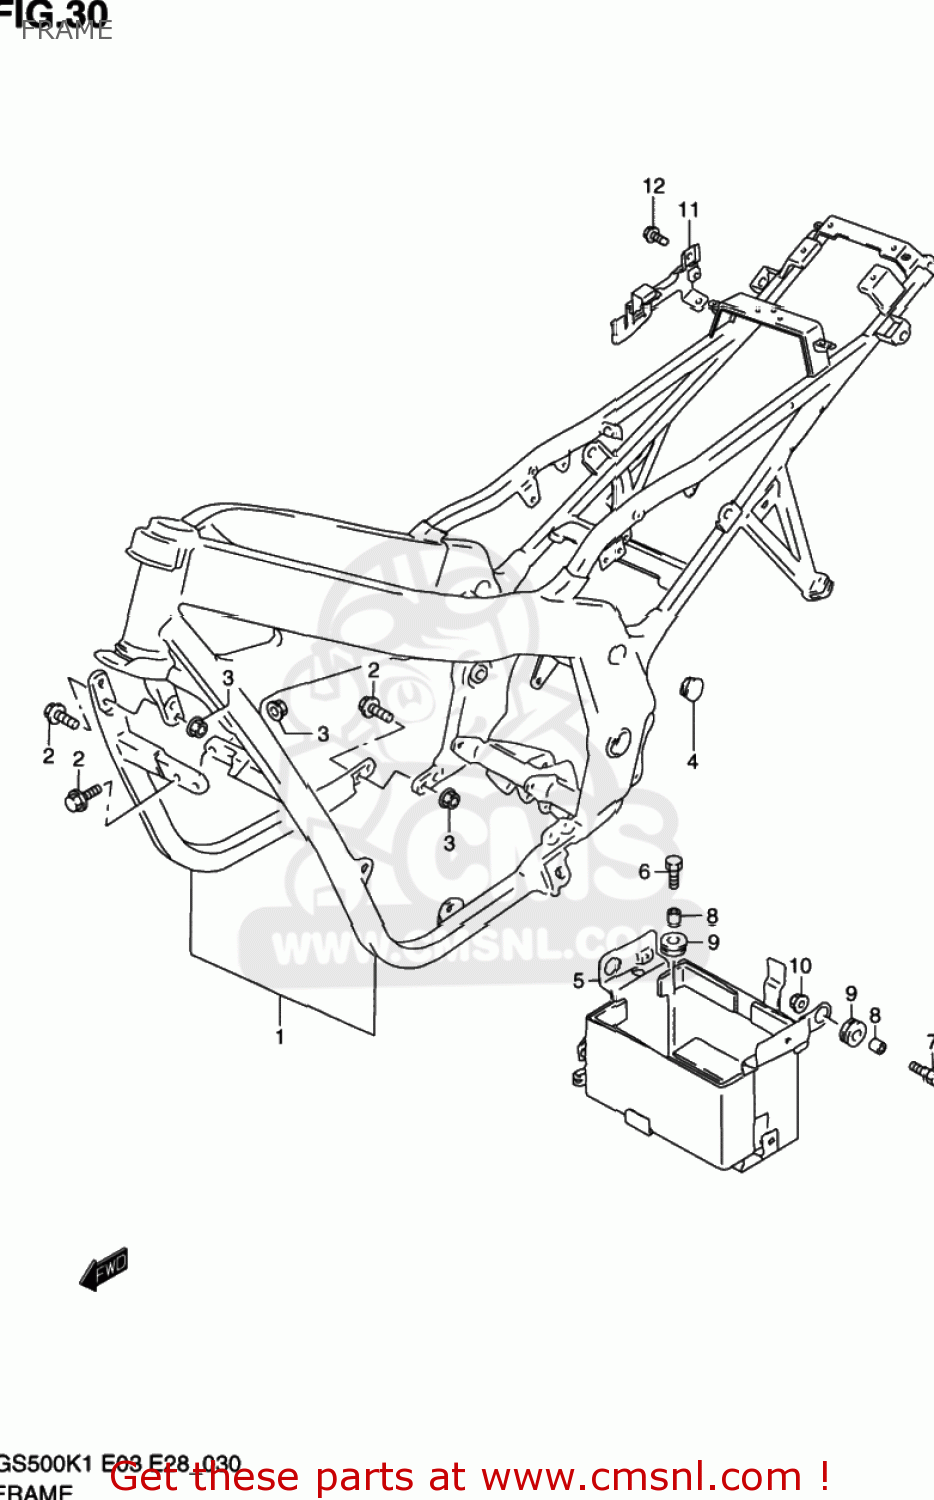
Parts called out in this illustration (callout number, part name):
1	FRAME
2	BOLT(10X35)
3	NUT
4	CAP,BODY FRAME
5	HOLDER,BATTERY
6	BOLT(6X20)
7	BOLT(6X16)
8	SPACER(6.1X9X7.5)
9	CUSHION
10	NUT
11	HOLDER,ELECTRIC PARTS
12	BOLT
